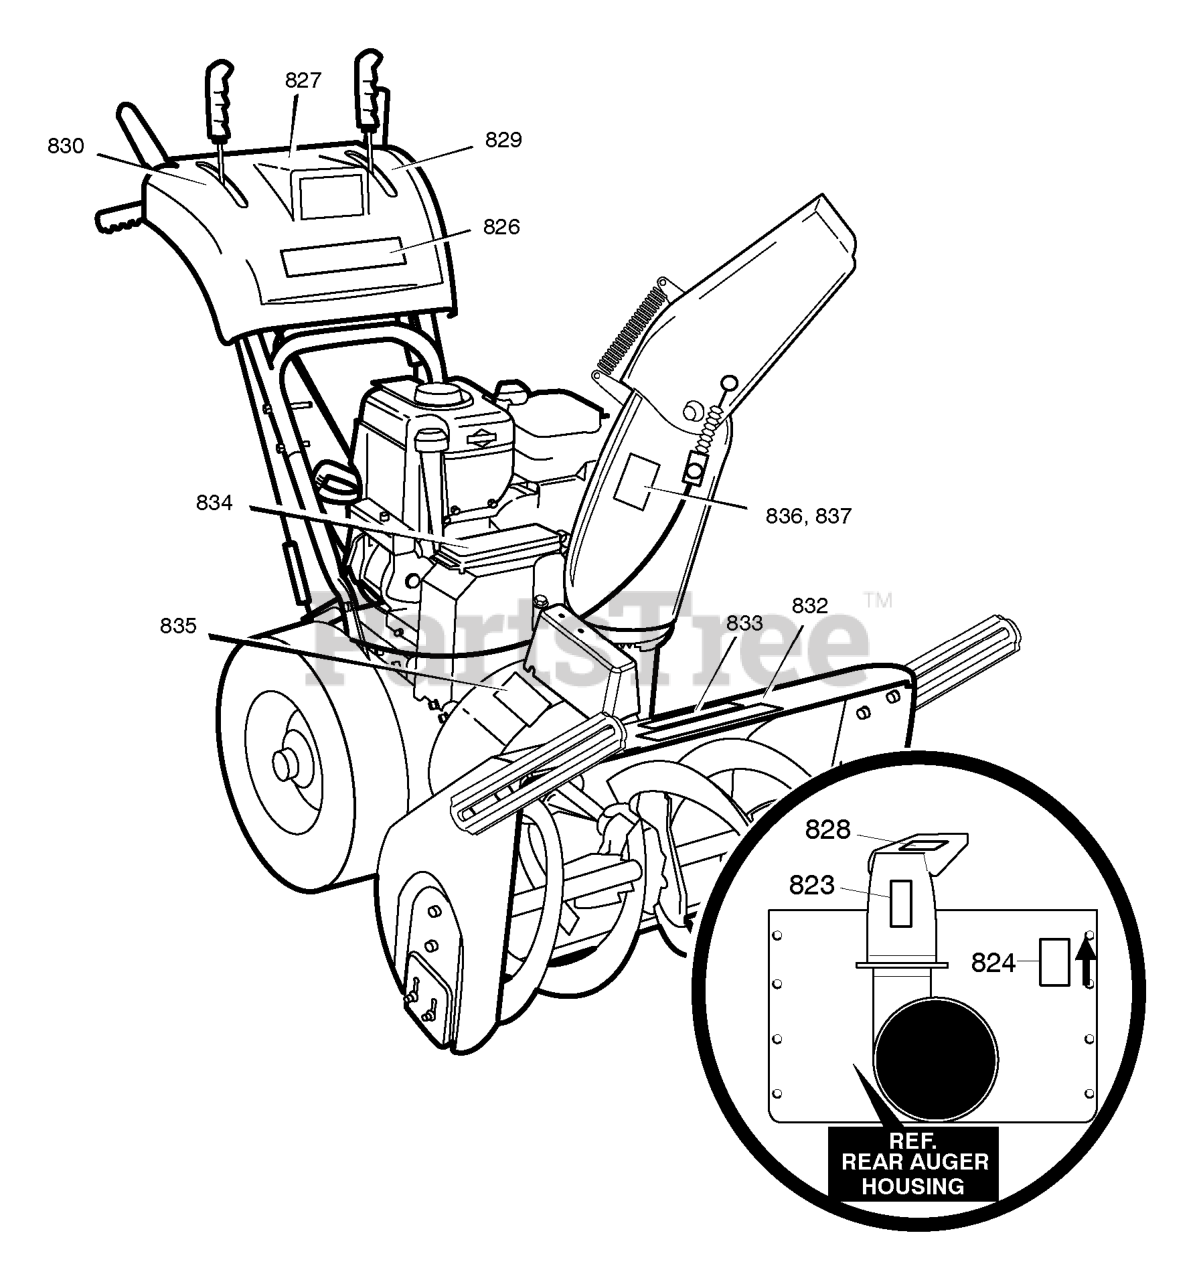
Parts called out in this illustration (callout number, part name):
823	DECAL, DANGER CHUTE HAND
824	DECAL, DANGER FOOT
826	DECAL, CRAFTSMAN
827	DECAL, SINGLE HAND CONTROL
828	DECAL, THROWN OBJECTS
829	DECAL, REMOTE CHUTE ELECTRIC
830	DECAL, TRANS
832	DECAL, CRAFTSMAN 11.5/31
833	DECAL, CLEAN & CLEAR BRUSH
834	DECAL, TOOLBOX INFORMATION
835	DECAL, PINCH POINT ELECTRIC
836	DECAL, POWER 2 STEER, ENGLISH
837	DECAL, POWER 2 STEER, FRENCH
